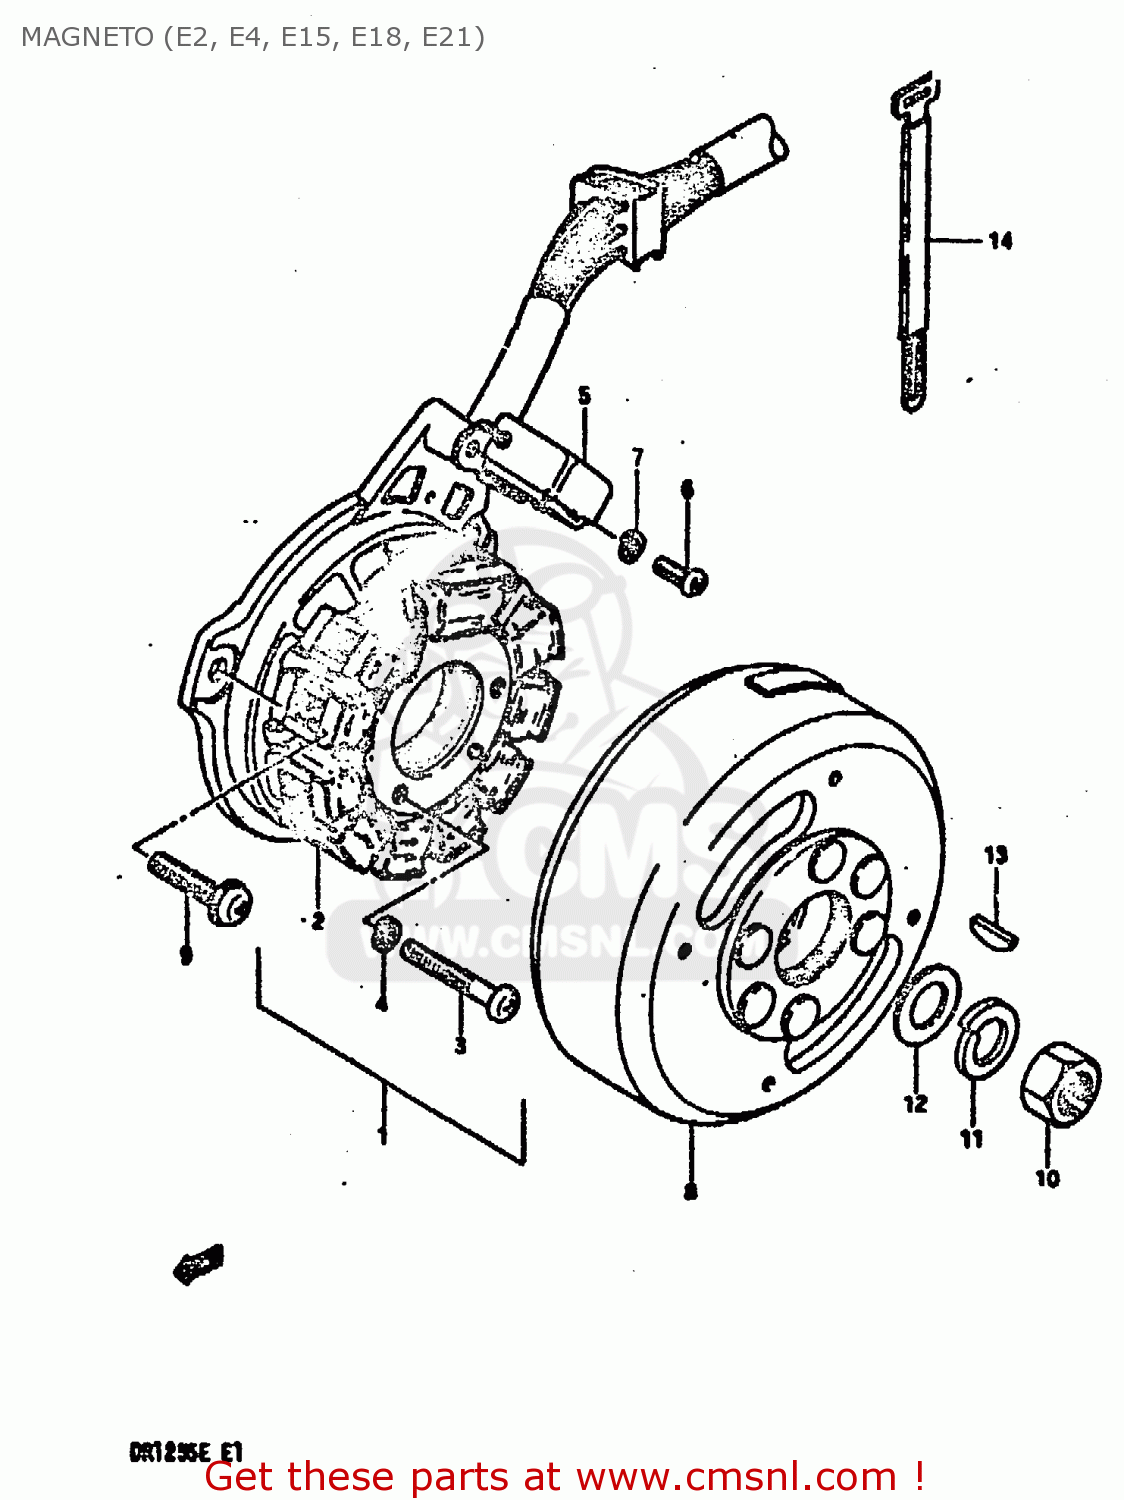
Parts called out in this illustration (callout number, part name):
1	STARTER ASSY
2	COIL,STARTER
3	SCREW
4	LOCK WASHER
5	COIL,CHARGING
6	SCREW
7	LOCK WASHER
8	ROTOR ASSY
9	SCREW(5X14)
10	NUT (10MM)
11	LOCK WASHER
12	WASHER
13	KEY
14	CLAMP L:110
